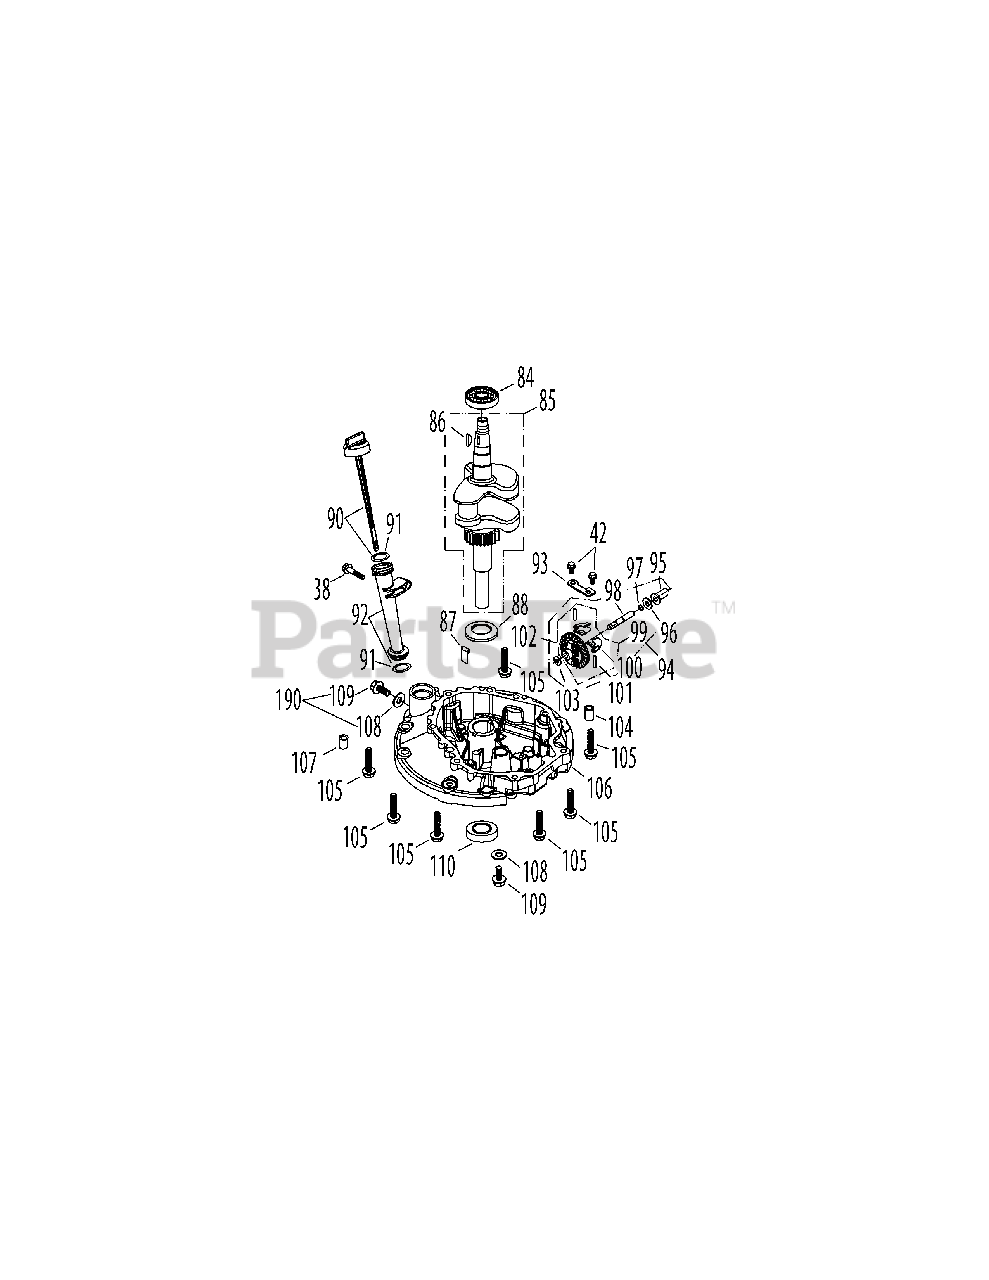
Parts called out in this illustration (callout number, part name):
38	Bolt M6×35
42	Bolt M6×14
84	Main Bearing
85	Crankshaft Assembly
86	Woodruff Key
87	Oil Return Seal
88	Crankshaft Thrust Washer
90	Dipstick Assembly
91	Dipstick and Oil Fill Tube O-Ring
92	Oil Filler Tube Assembly
93	Governor Gear Mounting Plate
94	Governor Gear/Shaft Assembly
95	Governor Slide Cap
96	Governor Slide Cap Washer
97	Governor Ring
98	Governor Gear Shaft
99	Governor Gear Assembly
100	Governor Fly Weight
101	Governor Fly Weight Pin
102	Governor Gear
103	Governor Gear Washer
104	Crankcase Cover Dowel 7×14
105	Coil/Sump Bolt M6x28
106	Crankcase Cover
107	Dowel Pin 9×14
108	Oil Drain Plug Washer
109	Oil Drain Plug
110	Lower Crankshaft Seal
190	Oil Drain Plug and Washer Ass'y
